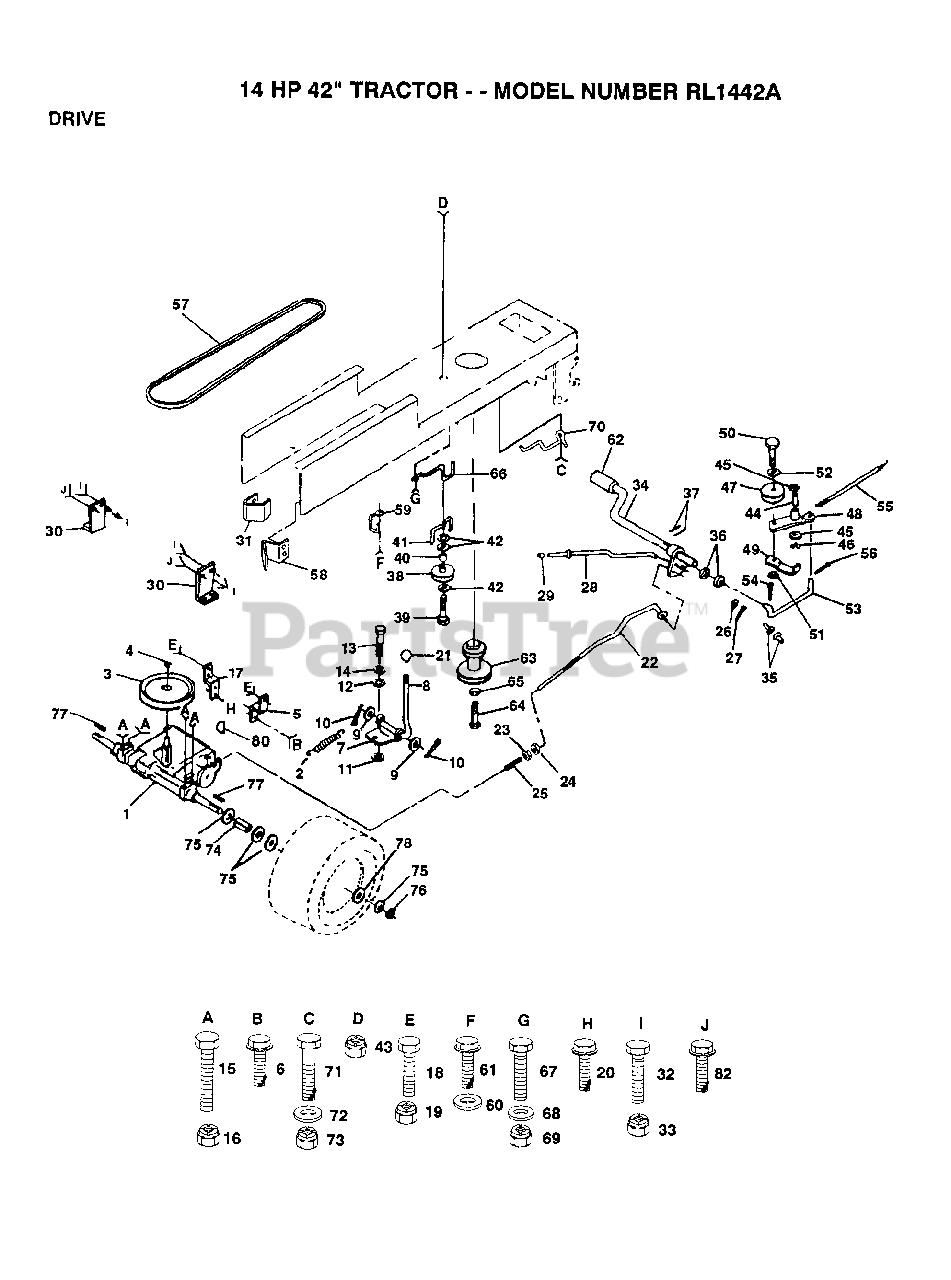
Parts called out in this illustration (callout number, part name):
3	PULLEY TRANS
5	STRAP TORQUE
6	SCREW
8	SHIFT ROD
9	WASHER
10	PIN COTTER 1/8
11	WASH-SHFT PLT LT
12	WASHER LT
14	LOCKWASHER
15	BOLT
17	STRAP TORQUE
20	SCREW
21	CONTROL KNOB LT
22	BRAKE ROD
23	NUT
24	NUT
25	SPRING ROD LT
26	WASHER
27	COTTER PIN
28	PARKING BRAKE ROD
30	TRANSAXLE MTG BKT
31	"KEEPER,BELT LH T"
32	BOLT
35	NYLON BEARING
36	WASHER LT
38	PULLEY.IDLER.FLAT
39	BOLT
40	SPACER T
41	BELT KEEPER LT
42	WASHER
44	"LY, BEARING"
45	WASHER LT
46	KLIP RING
48	ARM IDLER
49	RETAIN BELT
52	WASHER
53	"LINK, CLUTCH T"
54	COTTER PIN
55	"SPRING, RETURN LT"
56	COTTER PIN
58	"KEEPER,BELT RH T"
60	WASHER
61	SCREW
62	PEDAL COVER T
64	BOLT
65	LOCKWASHER
66	KEEPER.BELT.ENG.L
67	BOLT
68	WASHER
70	KEEPER BELT ENG
71	BOLT
72	WASHER
74	SPACER LT
75	WASHER
76	E-RING LT
77	SQUARE KEY
78	WASHER
82	SCREW
